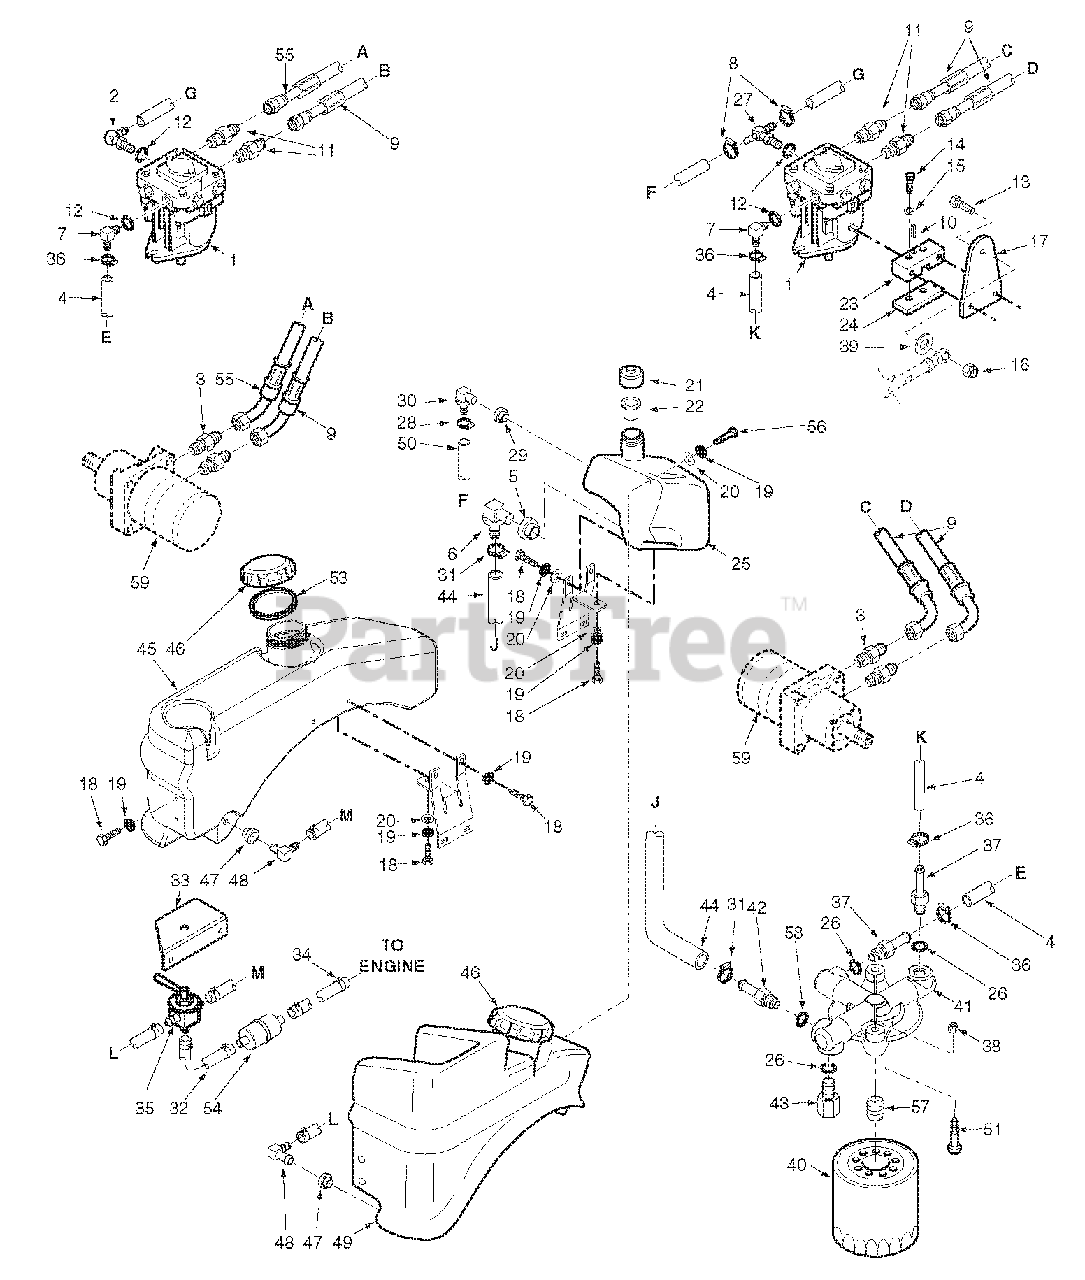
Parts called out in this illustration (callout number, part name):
1	Pump, BDP-10A-316 (LH)
1	Pump, BDP-10A-419 (RH)
2	Elbow, 90 Degree 9/16" O-Ring x 3/8" Hose
3	Fitting, 1/2" JIC x 5/8" O-Ring
4	Hose, 3/8" Pushlock (Specify length)
5	Bushing
6	Fitting
7	Elbow, 90 Degree 9/16" O-Ring x 3/8" Hose
8	Hose Clamp, .69" Dia.
9	Hose Assembly
10	Roll Pin
11	Fitting, 1/2" JIC x 1/2" O-Ring
12	O-Ring
13	Bolt, Hex Head 3/8-16 x 1-1/2"
14	Bolt, Hex Head 1/4-20 x 1-1/4"
15	Lockwasher
16	Nut, Elastic Stop 3/8-16
17	Control Lever
18	Bolt, Hex Head 5/16-18 x 3/4"
19	Lockwasher, 5/16"
20	Flatwasher, 5/16-.375 x .875 x .083
21	Cap, Hydraulic Tank
22	Insert, Filler Neck
23	Control Block
24	Clamp Plate
25	Hydraulic Tank Assembly w/Fittings
26	O-Ring, 9/16"
27	Tee Fitting, O-Ring to Barb
28	Clamp, .69" Max. / .25" Min. Dia.
29	Bushing
30	Elbow, 0.38" Hose
32	Fuel Hose, 1/4" ID Non-Perm.
33	Bracket Fuel Valve
34	Clamp, Fuel Hose 1/4" Hose ID
35	Valve, Fuel Shutoff
36	Clamp, .69" Max. / .25" Min. Dia.
37	Fitting, 9/16" O-Ring x 3/8" Hose
38	Nut, Serr. Flange 5/16-18
39	Flatwasher, 3/8-.391 x .938 x .105"
40	Oil Filter
41	Filter Head Assembly
42	Fitting, 3/4" O-Ring x 3/8" Hose
43	Plug, 9/16-18 O-Ring
44	Hose, Filter Inlet
45	Fuel Tank RH
46	Cap, Fuel Tank
47	Tank Bushing
48	Elbow, 90 Degree
49	Fuel Tank LH
50	Hose, 3/8" Pushlock 15" Long
51	Bolt, Hex Head 5/16-18 x 2"
52	Screw, 1/4-20 x 2"
53	Gasket, Gas Tank Cap
54	Fuel Filter
55	Hose Assembly
56	Bolt, Hex Head 5/16-18 x 1-1/2"
57	Nipple, Oil Filter 1.0-12 UNF-2A x 1-1/4"
58	O-Ring, 3/4"
59	Wheel Motor, Hydro-Gear
